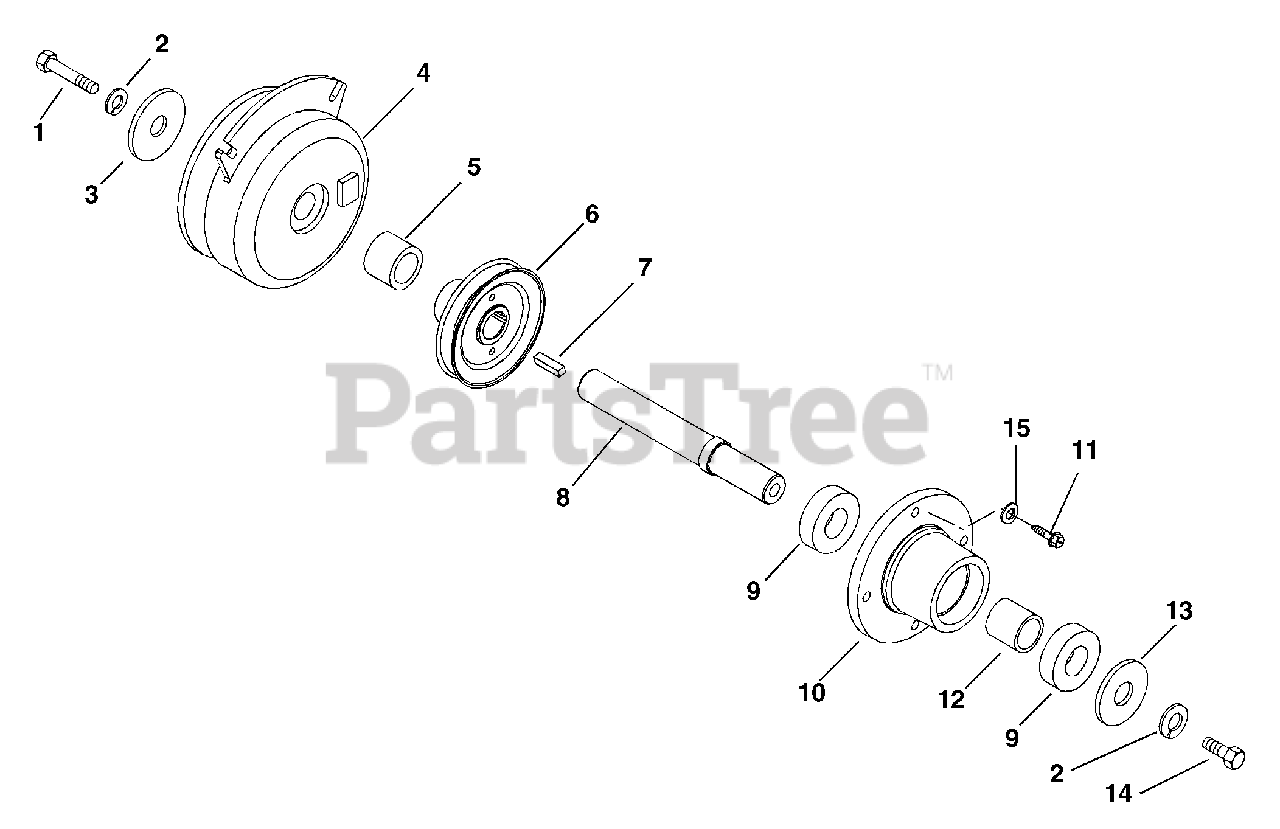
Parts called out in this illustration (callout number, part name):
1	Bolt-Hex .44-20 x 1.50 Grade 5
1	Bolt-Hex .44-20 x 2.50 Grade 5
2	Washer-Locking .44 x .109
3	Washer-Flat-Steel .469 x 2.00 x .25
4	Clutch-Electric/Brake
5	Spacer 1.004 x 1.500 x .740
6	Sheave-Jackshaft 4.50
6	Sheave- Jackshaft 4.50
7	Key-Square .25 x 1.00 x .25 SAE
8	Shaft-Jack
9	Bearing-Ball .984 x 2.04 x .59
10	Housing-Transmission Spindle
11	Screw-Tapping .31-18 x .75 Hex Washer Head
12	Spacer 1.00 x .253 x 1.26
13	Washer-Flat-Steel .463 x 1.38 x .25
14	Bolt-Hex .44-20 x 1.00 Grade 5
15	Washer-Flat-Steel .328 x 1.00 x .094
